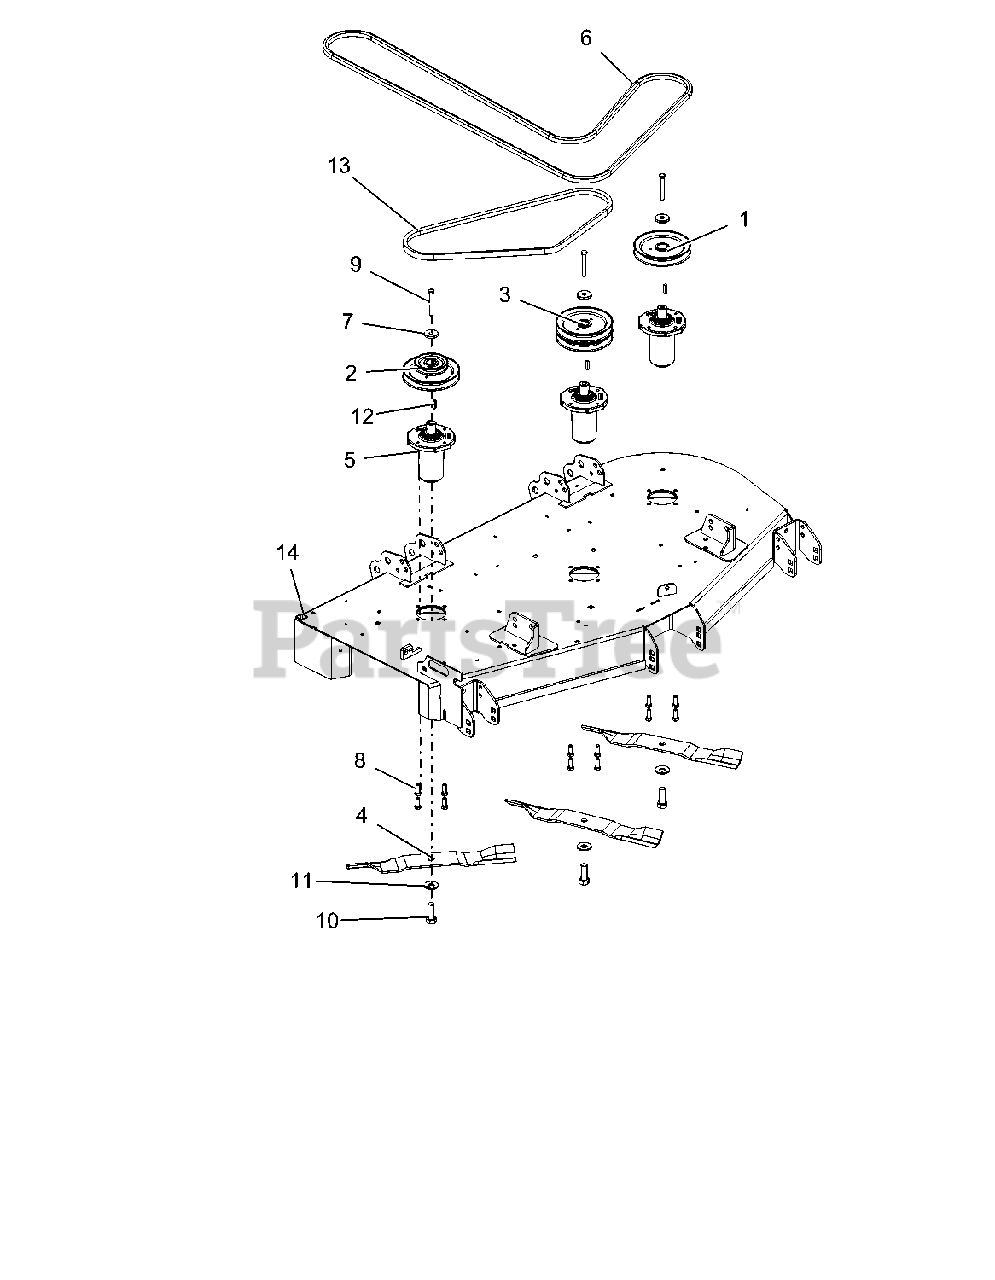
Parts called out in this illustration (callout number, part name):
1	PULLEY, SINGLE -1" ID X 6.00" OD-BLACK
2	PULLEY, DBL -1"IDX5.75"&3.50"OD-BLACK
3	PULLEY, DOUBLE -1" ID X 6.00" OD-BLACK
4	BLADE, 18"
5	SERVICE, ASM SPINDLE- DUCTILE
6	HEX BELT, BB WRAPPED
7	RETAINER, SHEAVE SPINDLE
8	BLT-HEX .38-16X1.00 GR5 YWZC EP30
9	BLT-HEX .38-16X2.75 GR8 YWZC
10	BLT-HEX .625-18X1.75 GR8 YWZC
11	WSHR, BLVL-.63X1.625X.14
12	KEY-SQ .250X.250X1.00 RC 40-50
13	BELT, B 56.00 RAW COGGED
14	KIT, 52" MOWER DECK W/SAFETY DECALS-RED
